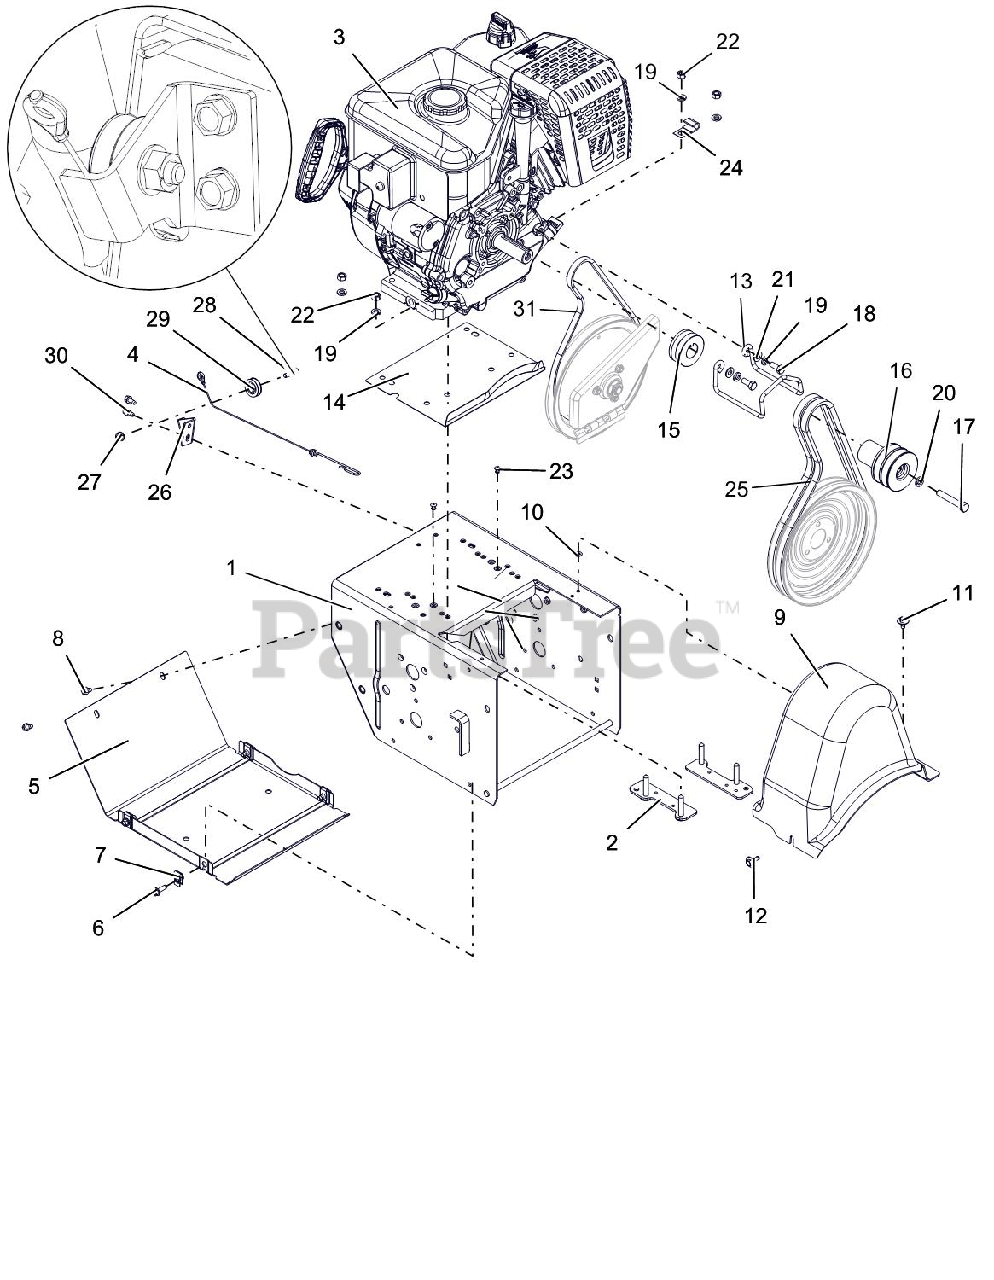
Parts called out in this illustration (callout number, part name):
1	FRAME, MAIN-DELUXE(WELDMENT)
2	STRAP, ENGINE-MEDIUM BLOCK
3	ENGINE, AX306 GEN 3 120V/60W
4	CABLE, LOWER TRACTION,SS & PRO
5	COVER, BOTTOM
6	BLT-HEX .25-20X.75 HWH YZ GR5
7	NUT-RTNR .25-20X.56
8	SCR-TAP .25-20X.50 HWH TR YWZ
9	COVER, BELT-LARGE
10	NUT-PUSH .25X.50 O.D.
11	SCR-TAP .25-20X.50 LGHWH TR YZ
12	SCR-TAP .25-20X.5 CAPTIVE
13	FINGER, BELT
14	BAFFLE, WATER - LARGE BLOCK
15	SHEAVE, DRIVE
16	SHEAVE, ATTACHMENT 2-GRV
17	BLT-HEX .38-24X2.25 YWZC GR5
18	BLT-HEX .31-24X.75 YWZC GR5
19	WSHR-LK .312X.097 HVY YWZC
20	@WSHR-LK .38X.094 REG YWZC
21	@WSHR-FL-STL.344X.688X.065YWZC
22	@NUT-HEX .31-18 YWZC
23	RVT-POP .187 YZ
24	J-CLAMP
25	V-BELT, HA-RAW EDGE (SET)
26	BRACKET, CABLE PULLEY
27	@NUT-LK-TOP-FLG .25-20 YWZC
28	BOLT, SHLDR-.375X.375X.25-20
29	PULLEY, CABLE
30	SCR-TAP .25-20X.50 HWH TR YWZ
31	V-BELT, 3L-WRAPPED
